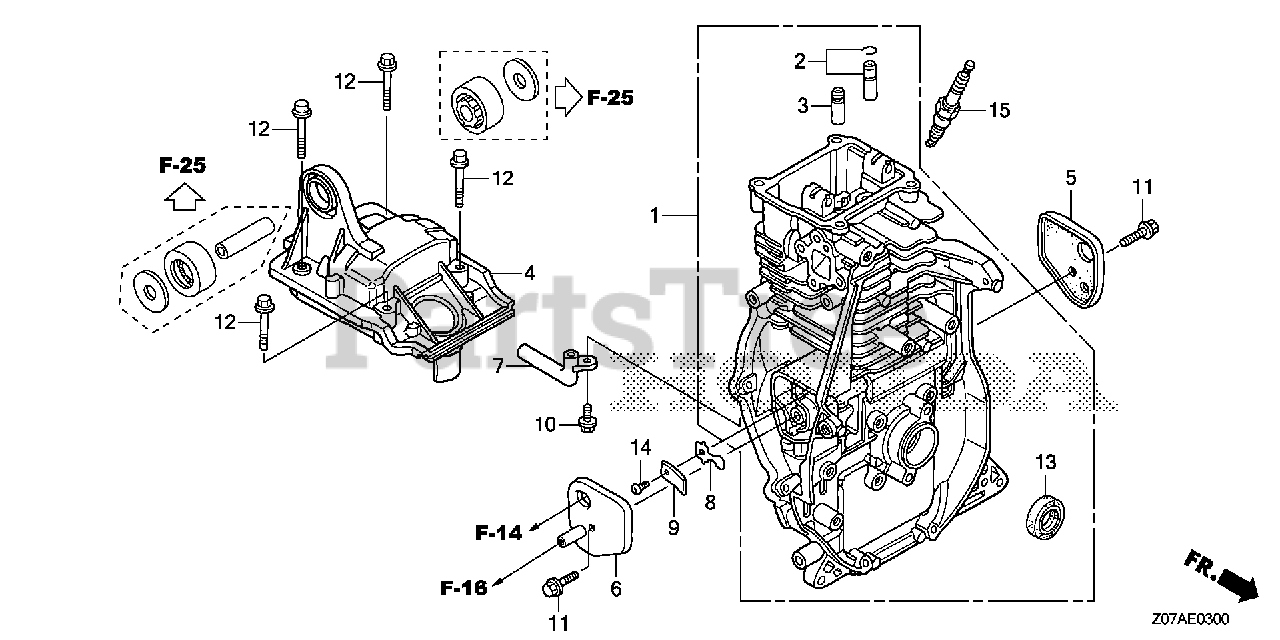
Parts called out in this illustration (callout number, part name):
1	CYLINDER ASSY.
2	GUIDE ASSY., EX. VALVE (OVER SIZE)
3	GUIDE, VALVE (OVER SIZE)
4	COVER, HEAD
5	COVER A, BREATHER
6	COVER B, BREATHER
7	PIPE, BREATHER
8	VALVE, OIL OUTLET
9	PLATE, STOPPER
10	BOLT (4X10)
11	BOLT, FLANGE (6X14) (CT200)
12	BOLT, FLANGE (6X28) (CT200)
13	OIL SEAL (20X32X6)
14	SCREW, PAN (3X5)
15	SPARK PLUG (CR4HSB) (NGK)
15	SPARK PLUG (CR5HSB) (NGK)
